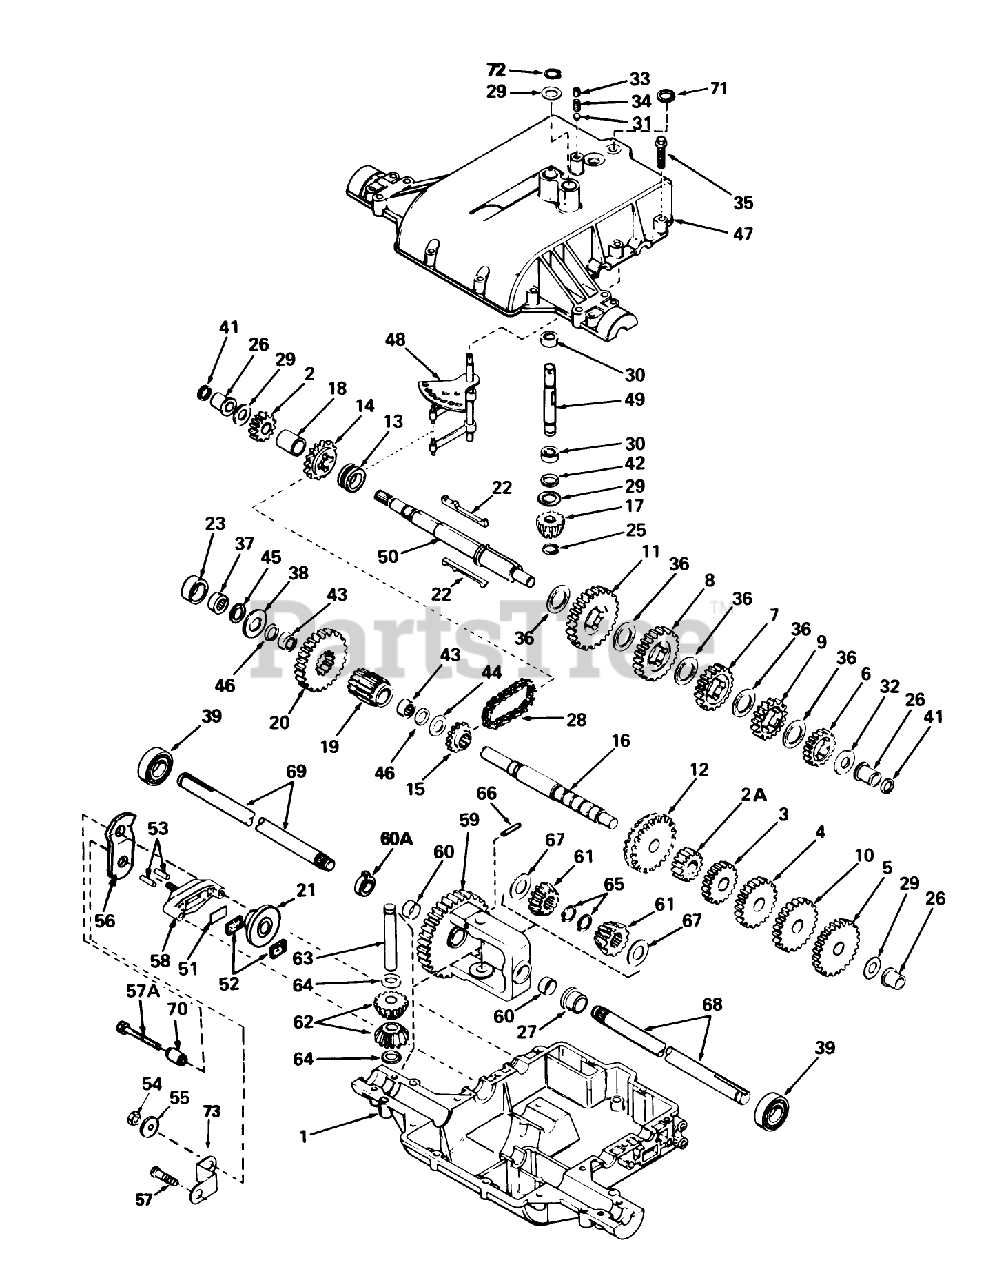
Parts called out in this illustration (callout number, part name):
1	Case-transaxle
2	Gear-Spur 15 Teeth
2A	Gear-Spur, 12 Teeth
3	Gear-Spur, 20 Teeth
4	Gear-Spur, 25 Teeth
5	Gear-Spur (30 teeth)
6	Gear-Spur 20 teeth
7	Gear-Spur, 25 Teeth
8	Gear-Spur, 30 Teeth
9	Gear-Spur (22 teeth)
10	Gear-Spur (28 teeth)
11	Gear-Spur, 37 Teeth
12	Gear-Bevel (42Teeth)
13	Collar-Shift
14	Sprocket-18 Teeth
15	Sprocket-9 Teeth
16	Shaft-Counter
17	Bevel Pinion-Input
18	Spacer
19	Pinion-Output
20	Gear-Output
23	Spacer
25	Ring-Retainer
26	Bushing-Flange
27	Bushing-Flanged
28	Chain-Roller #41
29	Washer
30	Bearing-Needle
31	Ball-Steel
32	Washer
33	Screw-Set
34	Spring
35	Ring Set (.020 O S)
36	Washer
37	Bearing-Needle
38	Washer-Flat
39	Bearing-Ball
41	Ring-Square Cut
42	O Ring
43	Bearing-Needle
44	Washer-Flat
45	Ring-Square Cut
46	Ring-Square Cut
47	Cover-Transaxle
48	Rod Fork Assembly
49	Shaft-Input
50	Shaft-Brake
51	Brake Pad Plate
52	Brake Pad
53	Dowel Pin
54	Locknut
55	Washer
56	Lever-Brake
57	Ring Set (.020 O S)
57A	Screw-Hex. Flange
58	Holder-Brake Pad
59	Gear Assy., Differential (Incl. 2 of No. 60)
60	Bushing
60A	Bushing
61	Gear Bevel
62	Gear Pinion
63	Drive Pin
64	Thrust Washer
65	Ring-Snap
66	Pin-Roll
67	Washer
68	Axle (14 7/8" Long)
69	Axle (13" Long)
70	Spacer
71	Cut Seal-Square
72	Ring-Snap
73	Bracket-Brake Lever
